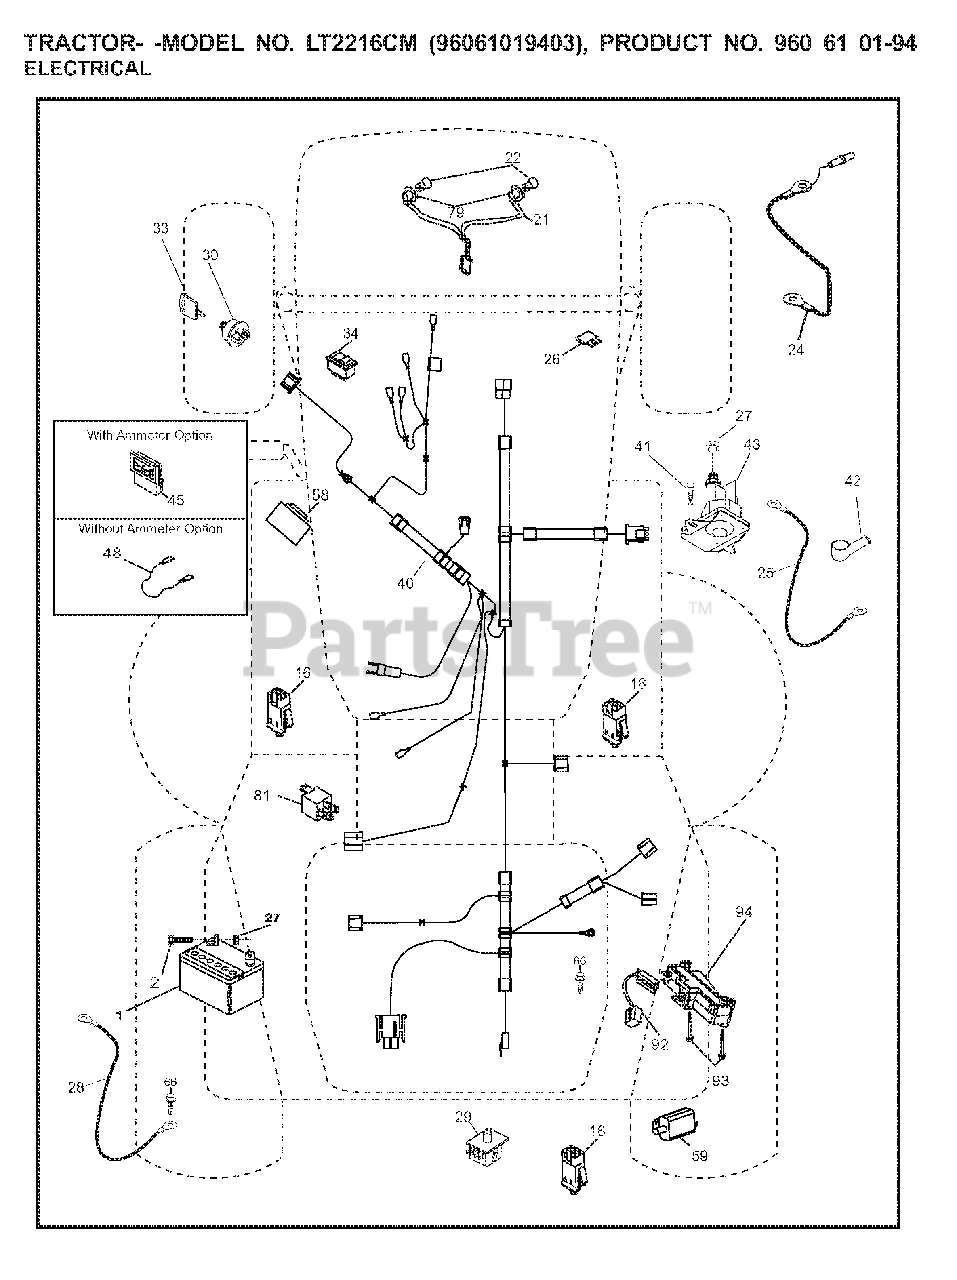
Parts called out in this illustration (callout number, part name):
1	REPL BY 532 12 38-99
16	SWITCH INTERLOOK PUSH-IN
21	HARNESS ASSY LIGHT
22	LIGHTBULB
24	BATTERY CABLE GT
25	CABLE BATTERY
26	FUSE 20AMP
27	NUT
28	CABLE GROUND
29	SWITCH.SEAT.DP W/RAMPS
30	SWITCH.IGN.DELTA.W.LGH.ROS
33	KEY.CHAIN.BLISTER.PACK.GEN.INT
34	SWITCH LT
42	TERMINAL COVER
43	SOLENOID.W/BRASS.PLUNG
58	BUZZER
79	BULB HOLDER ASM.
81	RELAY.ASSY.T
92	HARNESS.PIGTAIL.CONSLE
93	SCREW.PLASTITE
94	MODULE.REVERSE.ROS
